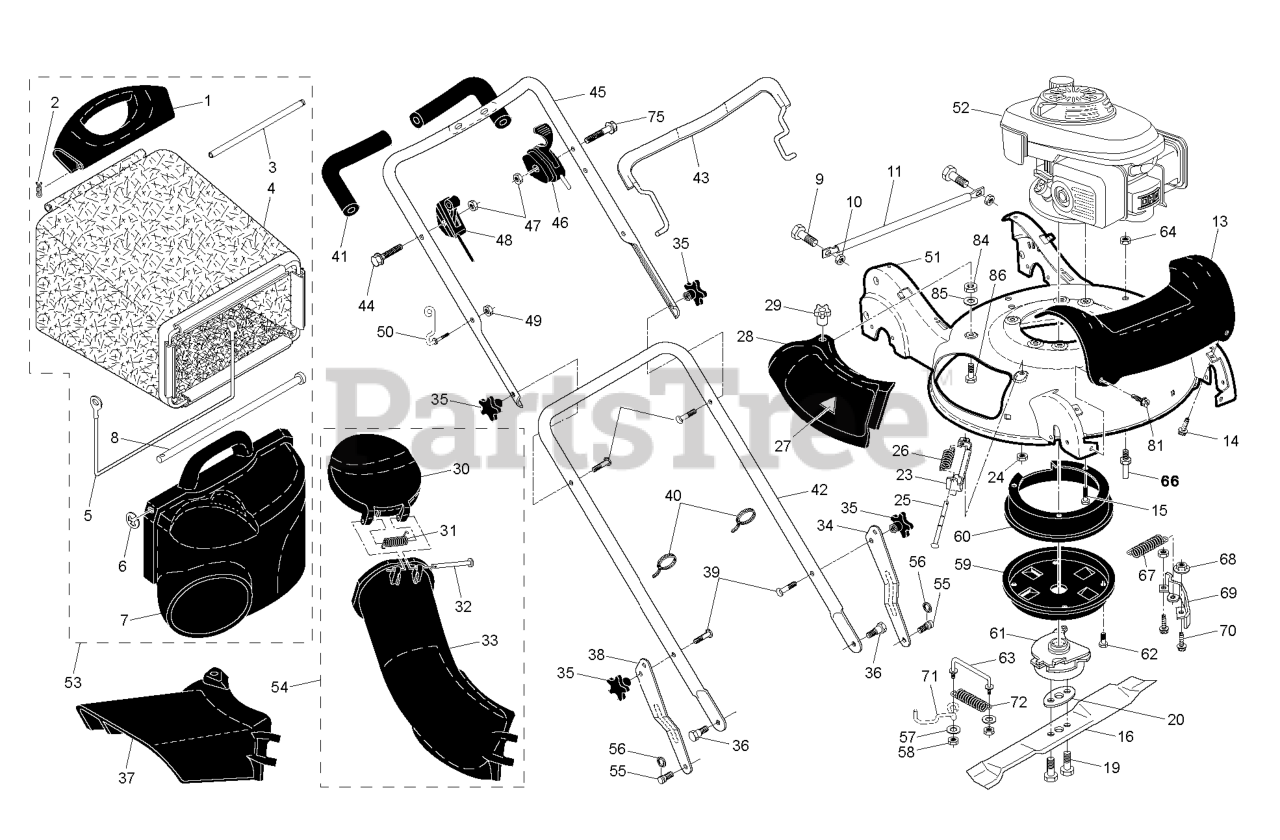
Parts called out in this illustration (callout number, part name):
2	Ball Bearing 6005-2rs
3	BALL BEARING 6010 2RS1
4	CIRCLIP SGH 47
8	RETAINING RING SGA 25
15	COLLAR SCREW
18	RETAINING RING
19	STEERING CHAIN
23	WIRE GUIDE
24	NUT
26	BRACKET STEERING ASSY WITH BUS
27	BRACKET STEERING ROD ASSY
28	RETAINING RING SGA 15
30	DRIVER STEERING WHEEL
33	FIXING PLATE
35	SPRING STEERING ADJUSTMENT
